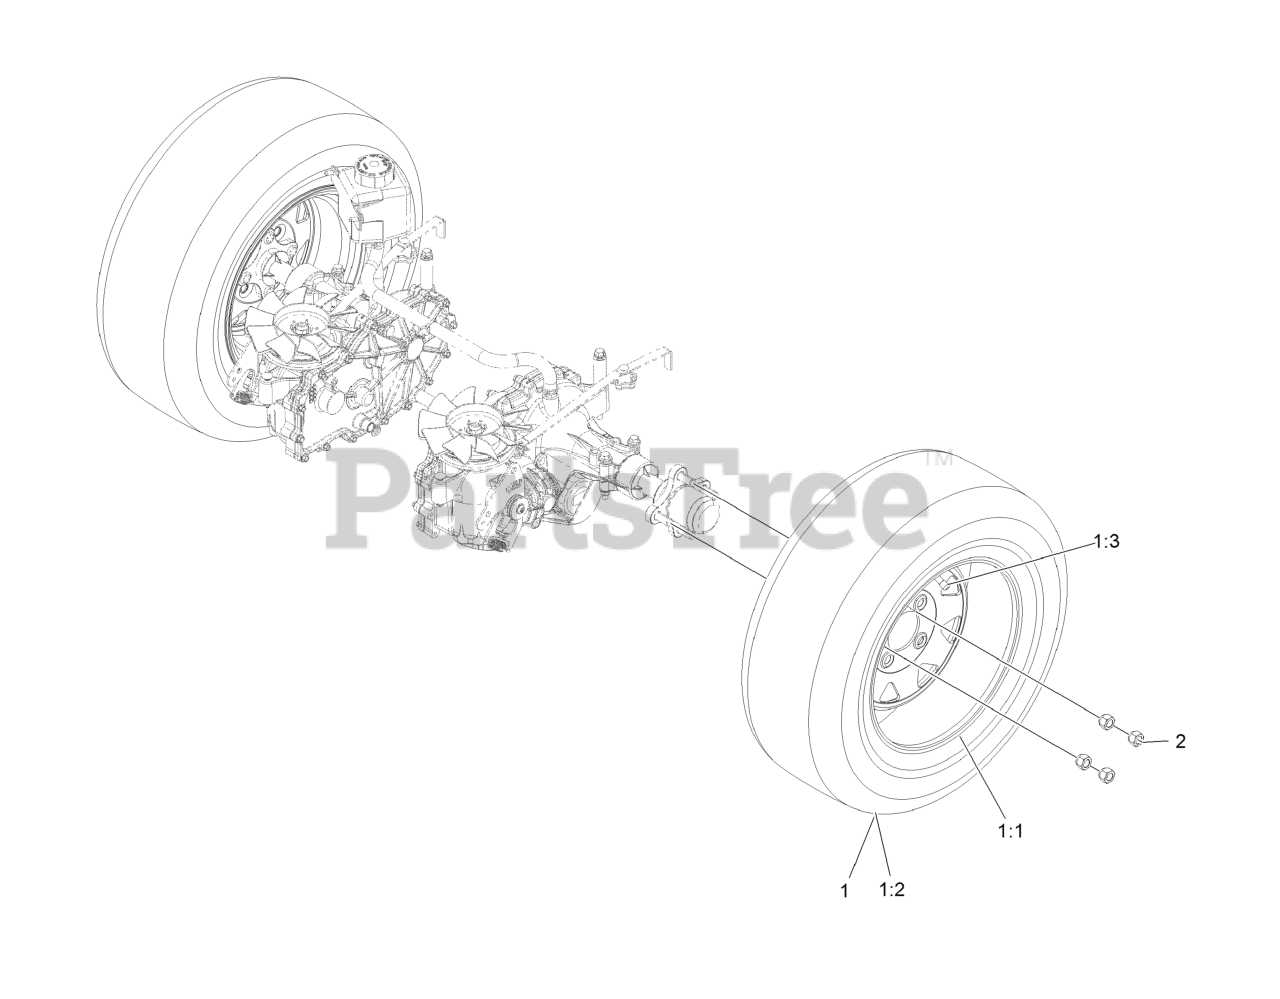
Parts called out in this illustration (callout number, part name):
1	WHEEL AND TIRE ASM
1:3	Stem-Valve
2	NUT-LUG
